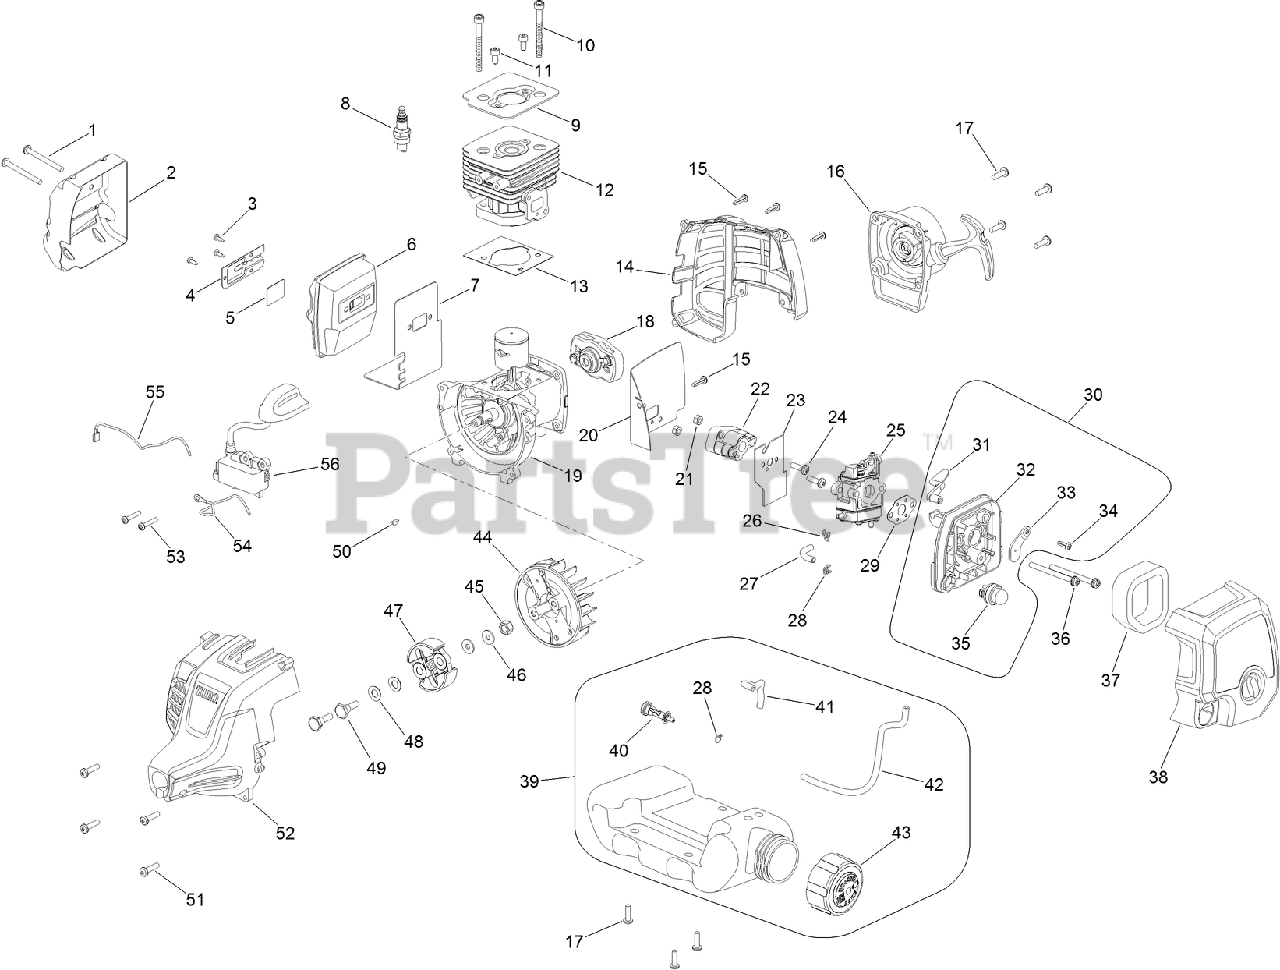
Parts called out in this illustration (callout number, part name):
1	SCREW-PH
2	SHIELD-HEAT
3	SCREW-PH
4	COVER-TRIMMER
6	MUFFLER ASM
7	GASKET-MUFFLER
8	SPARK PLUG
9	PLATE-CYLINDER
10	SCREW-SOCKET HEAD
11	SCREW-PH, TORX
14	HOUSING-ENGINE, REAR
17	SCREW-PH
18	PULLEY ASM
19	CRANKCASE ASM
22	INSULATOR-DAM, HEAT
24	SCREW-PH
25	CARBURETOR ASM
26	CLIP-HOSE
27	LINE-FUEL
28	CLIP-HOSE
30	FILTER HOUSING ASM
31	LEVER-CHOKE
32	PLATE-CARBURETOR
33	PLATE-CHOKE
34	SCREW-PH
35	PRIMER ASM
36	SCREW-PH
37	ELEMENT-FILTER, AIR
38	COVER-INTAKE, AIR
39	FUEL TANK ASM
40	FILTER-FUEL
41	HOSE-FUEL
42	HOSE-FUEL
43	CAP-FUEL
45	NUT-ROTOR
48	WASHER-CURVED
49	SCREW-CLUTCH
51	SCREW-PH
52	HOUSING-ENGINE, FRONT
53	SCREW-PH
54	WIRE-LEAD, RED
55	WIRE-LEAD, BLACK
